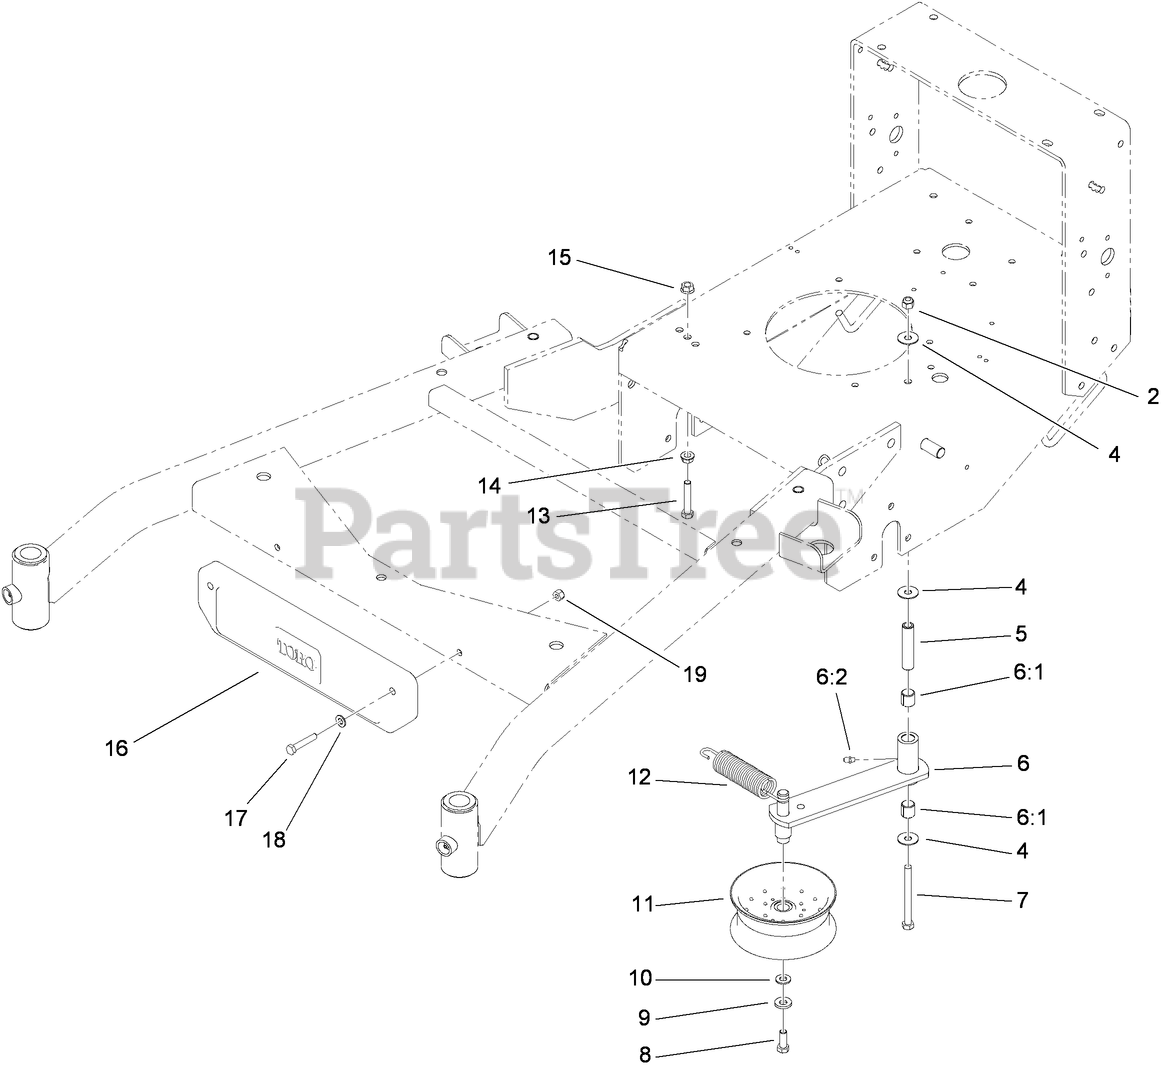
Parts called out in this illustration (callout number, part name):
2	NUT-LOCK, NI
4	WASHER
5	TUBE-IDLER
6	IDLER ARM ASM
6:1	SLEEVE-BEARING
6:2	FITTING-GREASE
7	SCREW-HH
8	SCREW-HH
9	WASHER-BELLEVILLE
10	WASHER-FLAT
11	PULLEY-IDLER
12	SPRING-EXTENSION
13	SCREW-HH
14	NUT-HHF, WHIZ
15	NUT-HF
16	WEIGHT-CAST
17	SCREW-HH
18	WASHER-PLAIN
19	NUT-LOCK, NI
